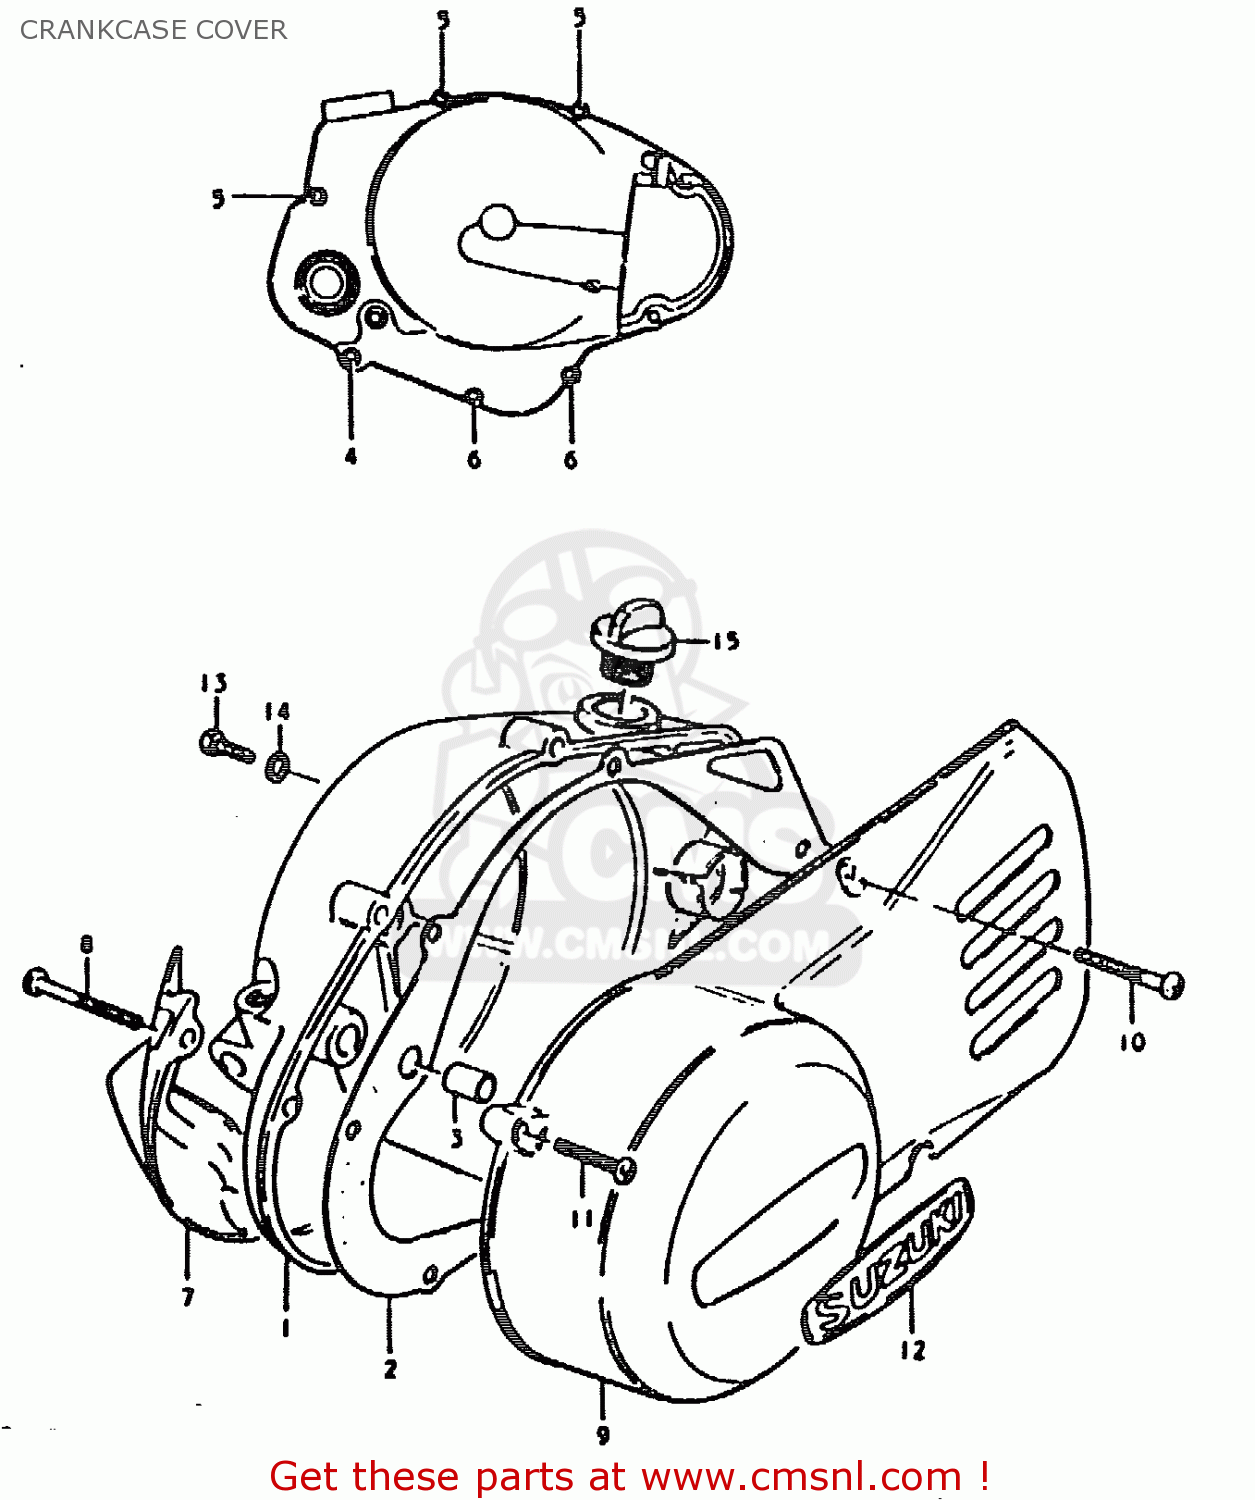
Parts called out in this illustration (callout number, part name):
1	COVER,CLUTCH
2	GASKET,CLUTCH COVER (MCA)
3	PIN
4	SCREW (6X45)
5	SCREW
6	SCREW
7	COVER,CLUTCH RELEASE A
8	SCREW
9	COVER,MAGNETO
10	SCREW 6X30
11	SCREW
12	EMBLEM,MAGNETO COVER
13	SCREW(6X10)
14	GASKET(6.2X11X1) (NAS)
15	PLUG
